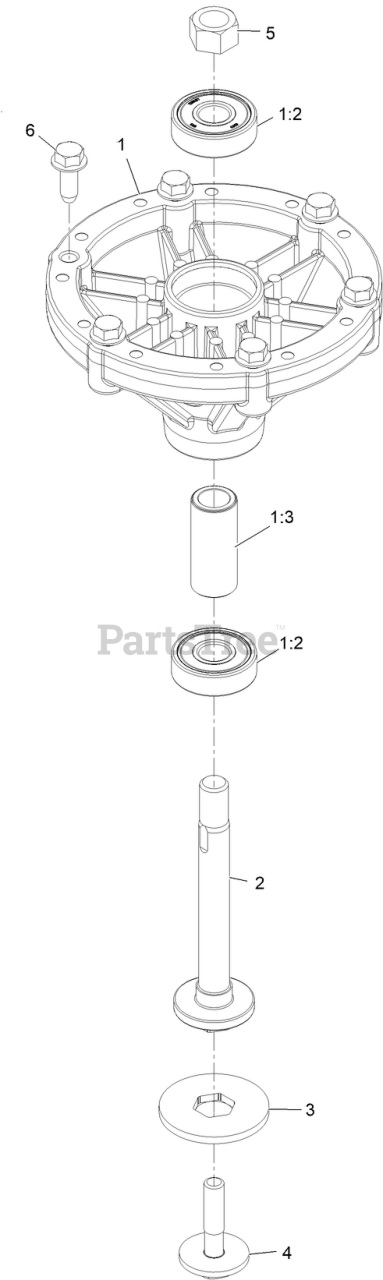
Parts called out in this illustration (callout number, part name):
1	ASM-CUTTER HOUSING
1:2	BEARING
1:3	SPACER-BEARING
2	SPINDLE-HEX PILOT
3	WASHER-HEX BLADE DRIVE
4	BOLT-BLADE, SEM
5	NUT-HEX
6	SCREW-FORMING, THREAD
